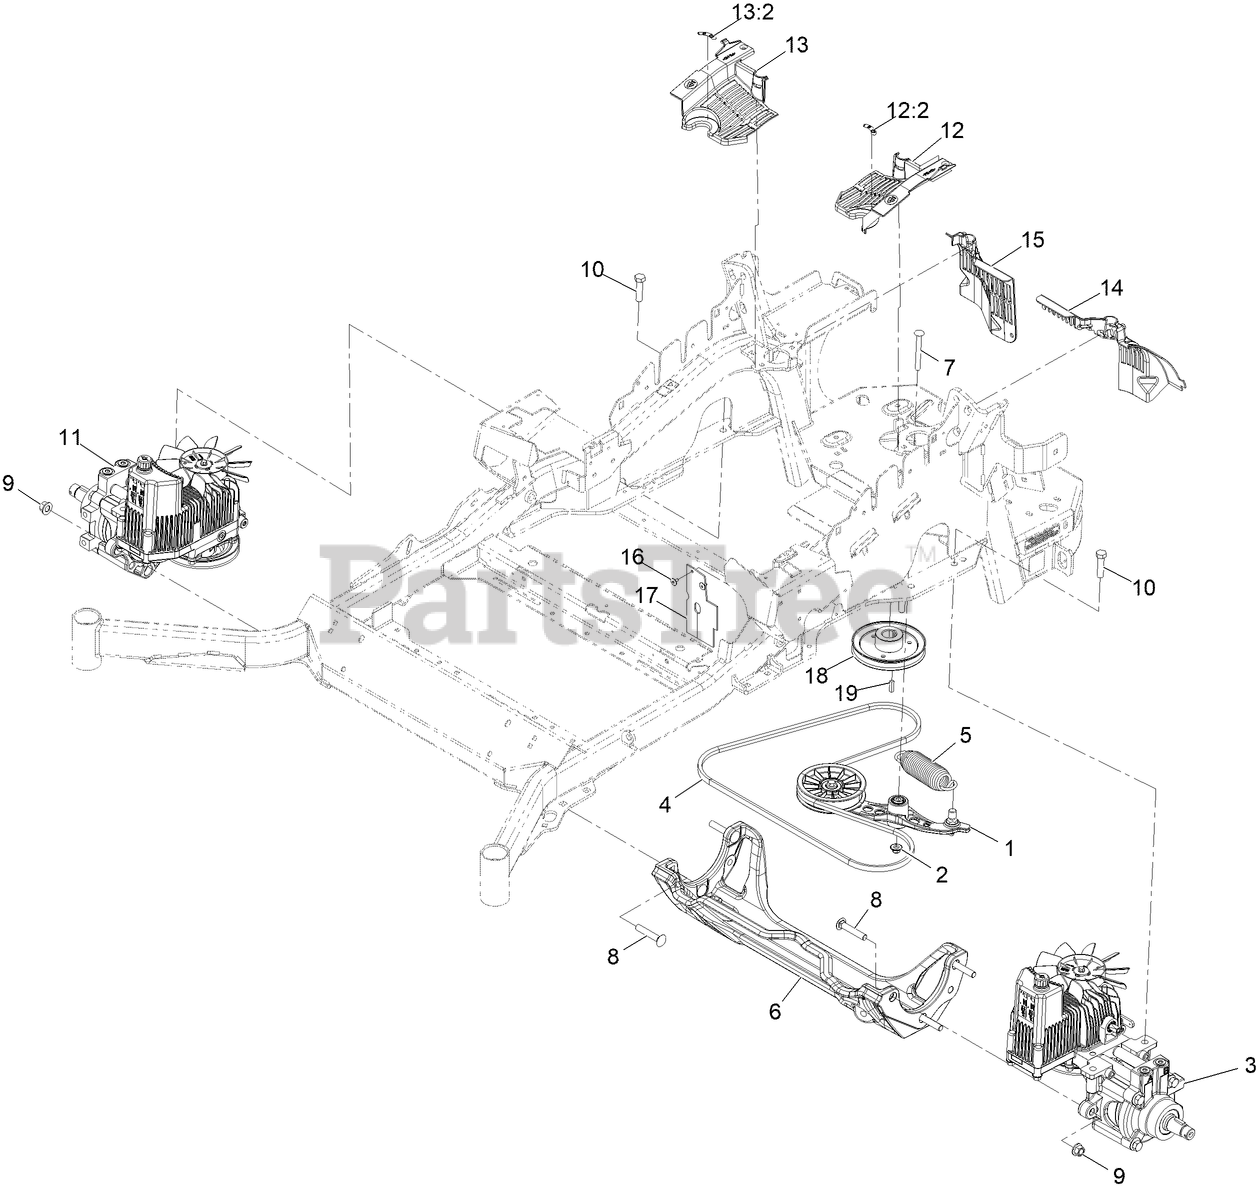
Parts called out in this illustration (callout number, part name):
1	PUMP IDLER ASM
2	Nut-Nyloc 3/8-16 Flg
3	HYDRO-LH
5	SPRING-EXTENSION
6	CRADLE-HYDRO
7	BOLT-SHOULDER, CARRIAGE 3/8-16 X 3 1/2
8	SCREW-CARR
9	Nut-Lock 1/2-13
10	SCREW-HH
11	HYDRO-RH
12	LH HYDRO GUARD ASM
12:2	DECAL-OIL, HYDRO
13	RH HYDRO GUARD ASM
13:2	DECAL-OIL, HYDRO
14	GUARD-HYDRO, REAR LH
15	GUARD-HYDRO, REAR (RH)
16	RIVET-POP
17	DEFLECTOR-AIR FLOW
18	SHEAVE, W/HUB
